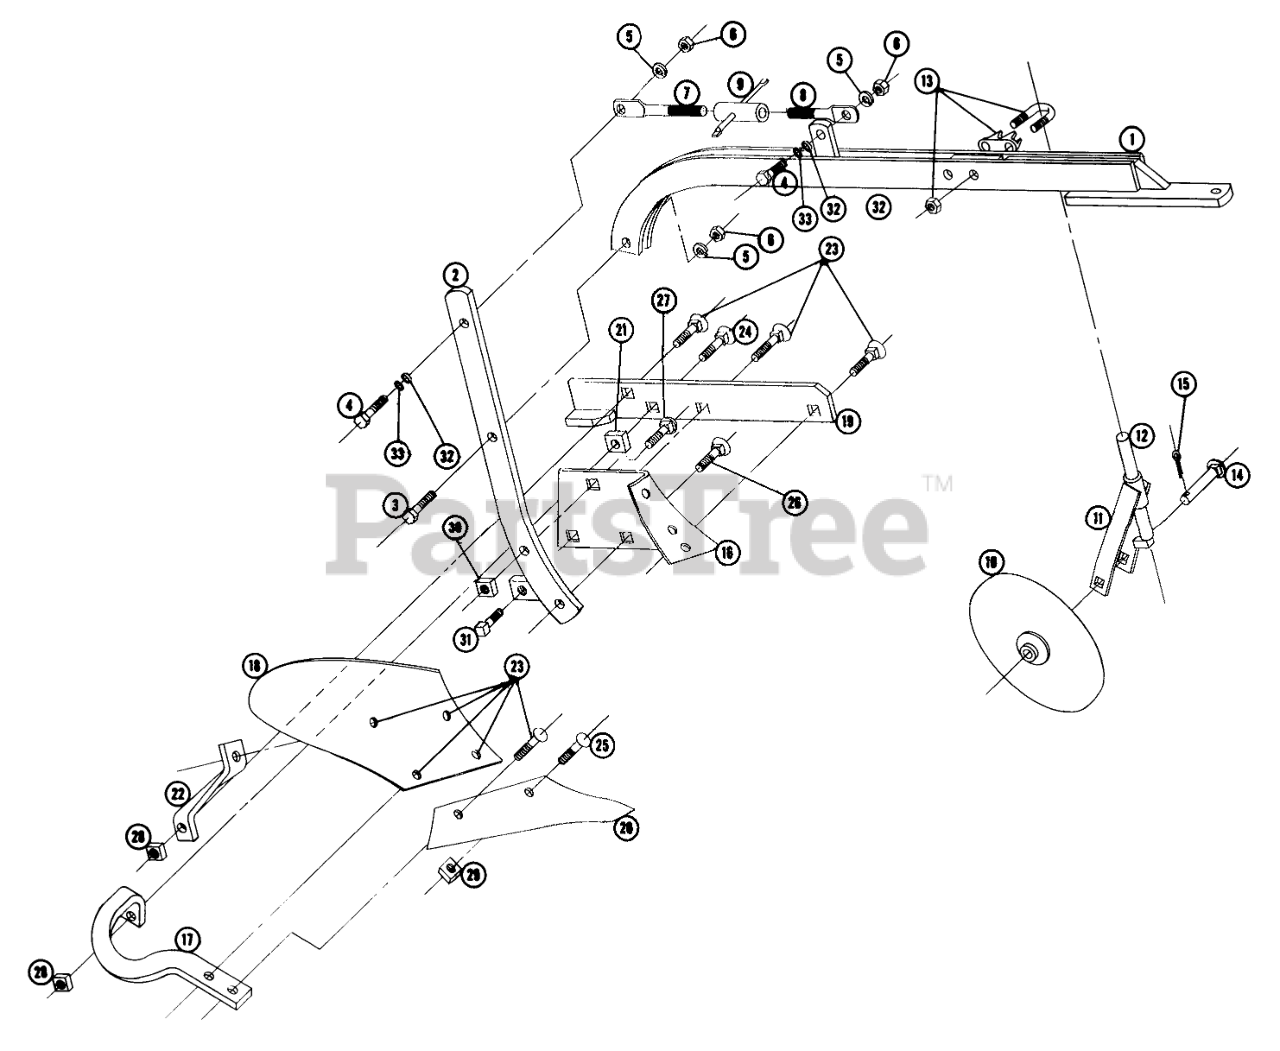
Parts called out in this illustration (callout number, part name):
1	Ass-y.-Beam
2	Standard Ass-y.
3	Bolt Hex 1/2-13 x 1 1/2
4	Bolt-Hex 1/2-13 x 2
5	Lockwasher
6	Locknut-1/2-13
9	Coupling-Adjusting
10	Colter Blade Assembly
11	Standard Assembly
12	Ass-y.-Standard-Coulter
13	Ass-y. "U" Bolt-Clamps-Nuts
14	Pin-Pivot
15	Cotter Pin 3/16 x 1
16	Frog
17	Spreader
18	Moldboard
19	Ass-y.-Landslide Heel
20	Point
21	Spacer-Spreader
22	Brace-Moldboard
23	Bolt-Plow 3/8-16 x 1
24	Plowbolt 3/8-16 x 1-1/2
25	Bolt-Plow #3 Hd. 7/16 x 1-1/4
26	Bolt-Plow #3 Hd. 1/2-13 x 1 3/4
27	Bolt-Carriage 1/2-13 x 1 3/4
28	Nut-Sq. 3/8-16
29	Nut-Sq. 7/16-14
30	Nut-Sq. 1/2-13
31	Bolt-Square Hd. 1/2-13 x 1
32	5353 GILSON LGT WEI
33	Washer-Flat
